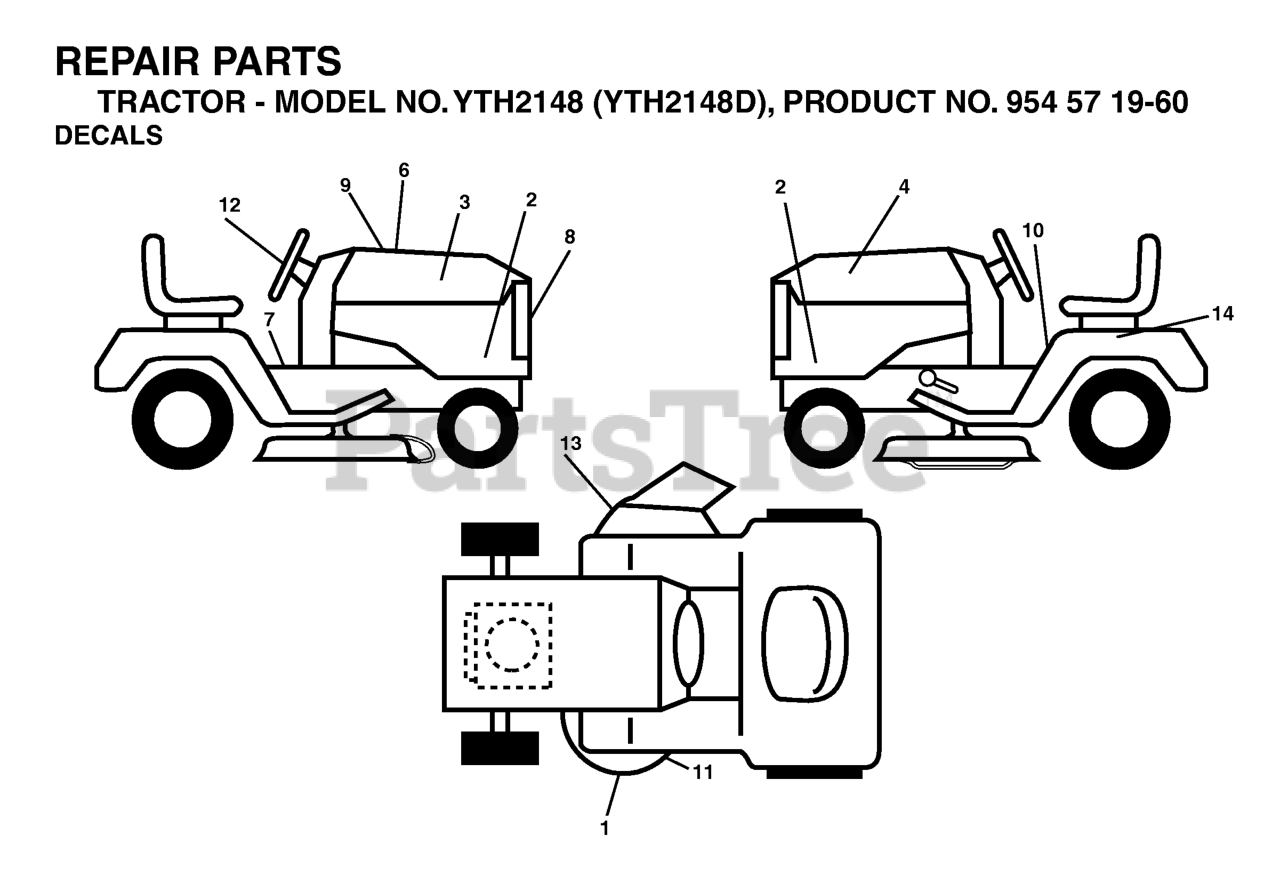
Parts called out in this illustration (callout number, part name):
6	DECAL HOOD CUST. RESP.
10	DECAL FENDER DANGER
11	DECAL V-BELT SCHEMATIC
12	DECAL.STEERING.HUSQ.BLUE
13	DECAL.WARN.KEEP.HAND.AWAY
14	DECAL BTRY SYMBOLS
